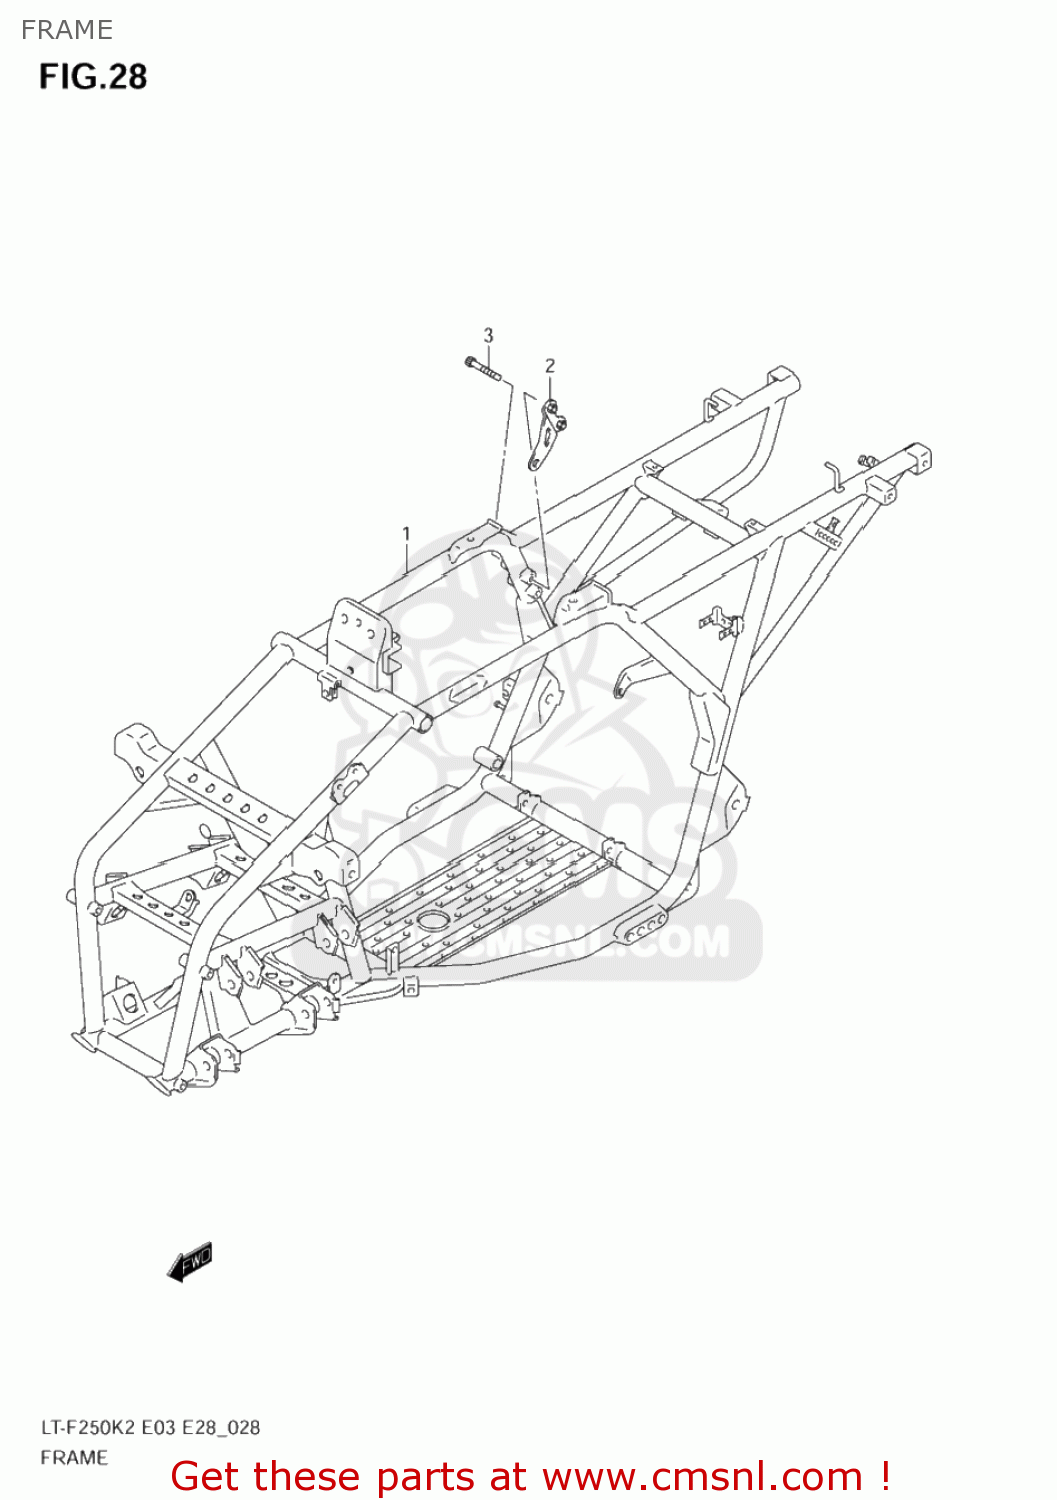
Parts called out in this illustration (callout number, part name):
1	FRAME(BLACK)
2	PLATE,ENG MTG RR,R
3	BOLT
